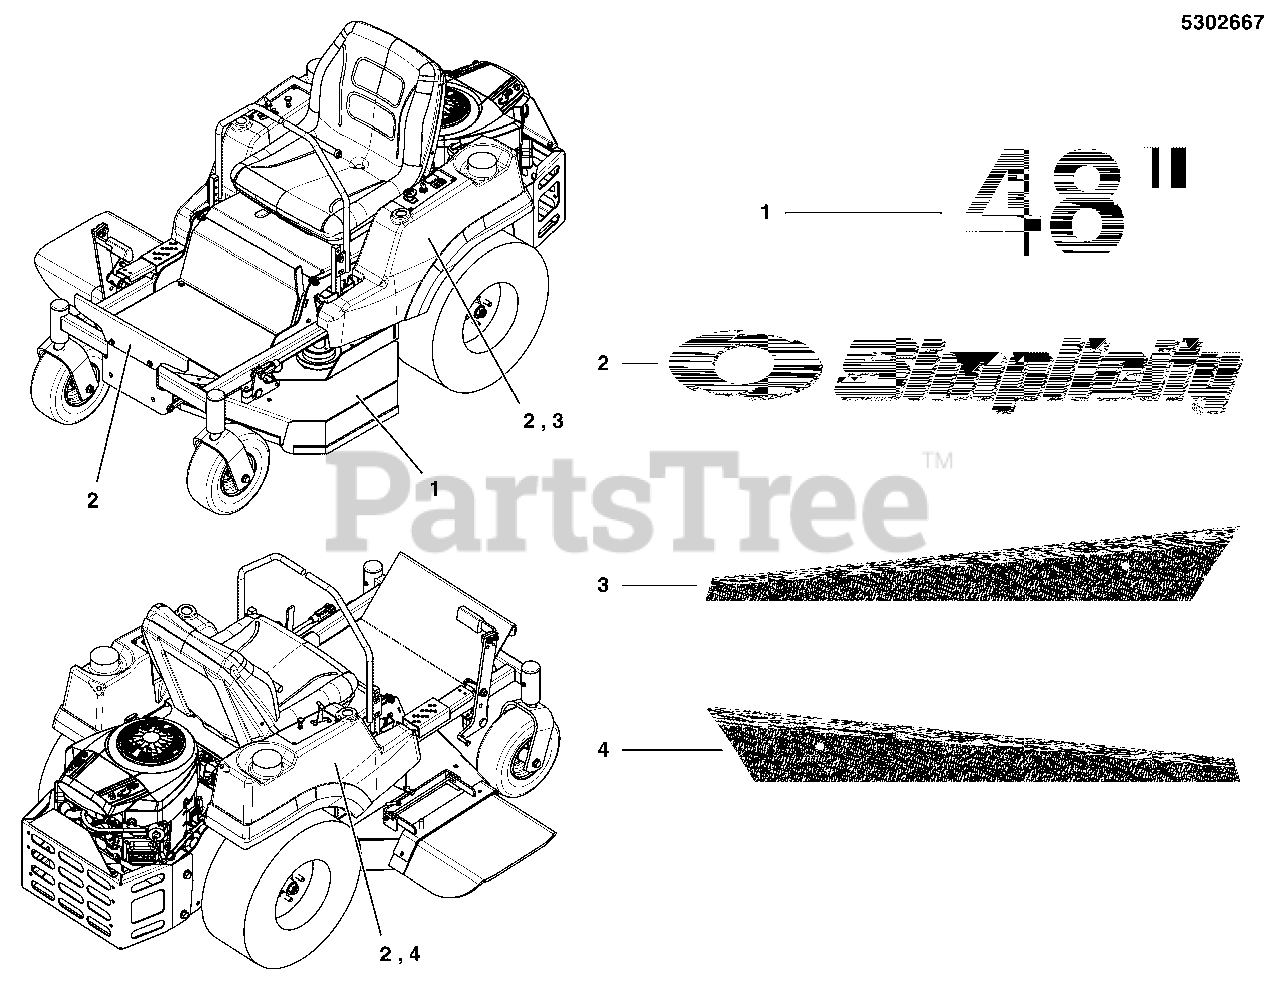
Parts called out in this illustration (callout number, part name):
1	DECAL, 48
2	DECAL-SIMPLICITY SILVER & BLUE W/ICON
3	DECAL-LH STRIPE CONSUMER Z
4	DECAL-RH STRIPE CONSUMER Z
